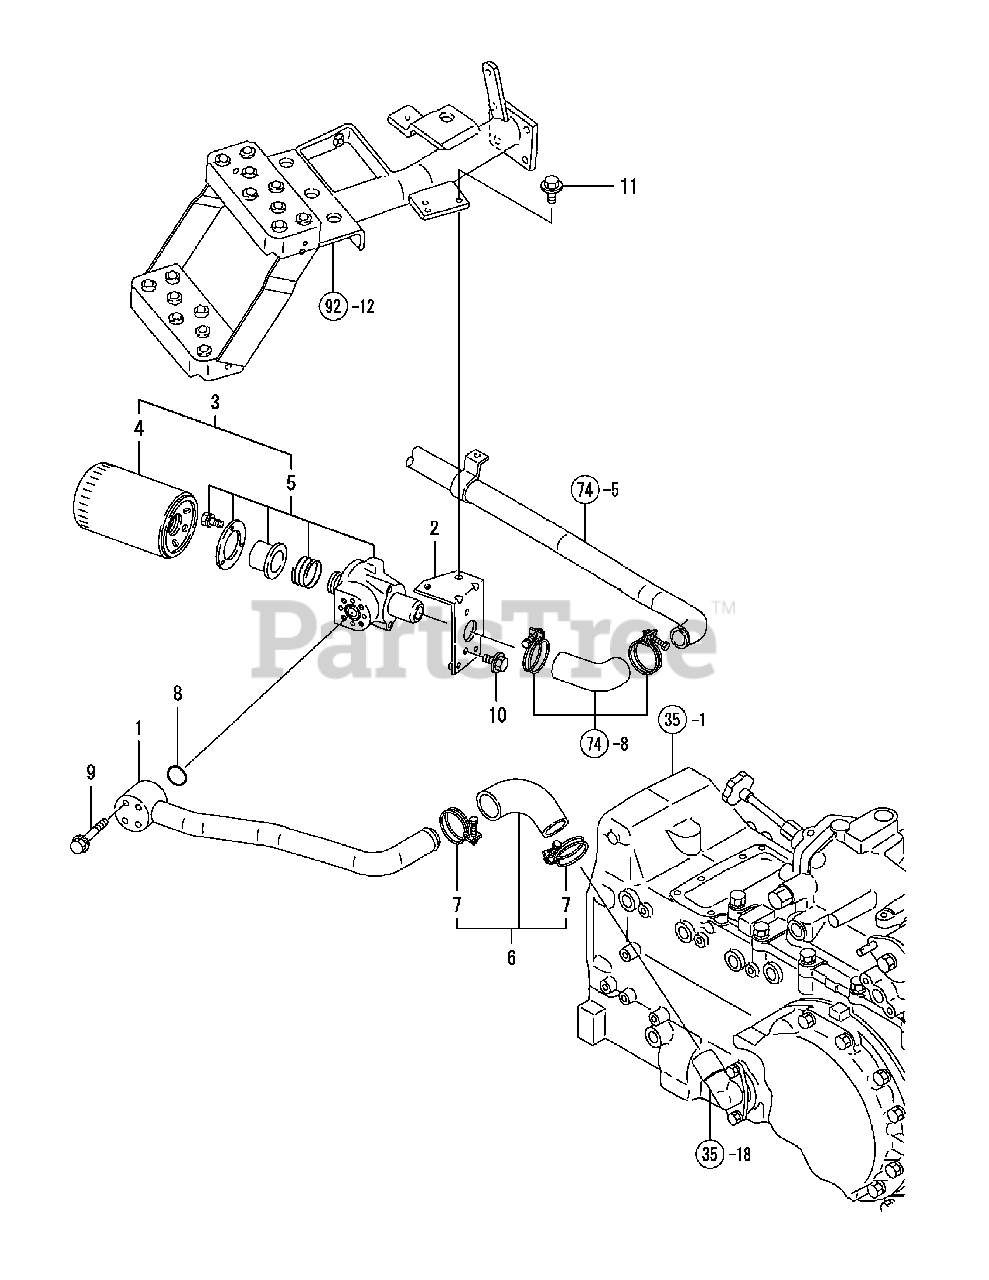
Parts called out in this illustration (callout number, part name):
2	BRACKET, STRAINER
3	OIL FILTER ASSY
5	COVER ASSY, FITER
6	HOSE ASSY,SUCTION
8	O-RING 1A G-25.0
9	BOLT M 6X 60 PLATED
10	BOLT M 8X 16 PLATED
11	BOLT M 8X 20 PLATED
